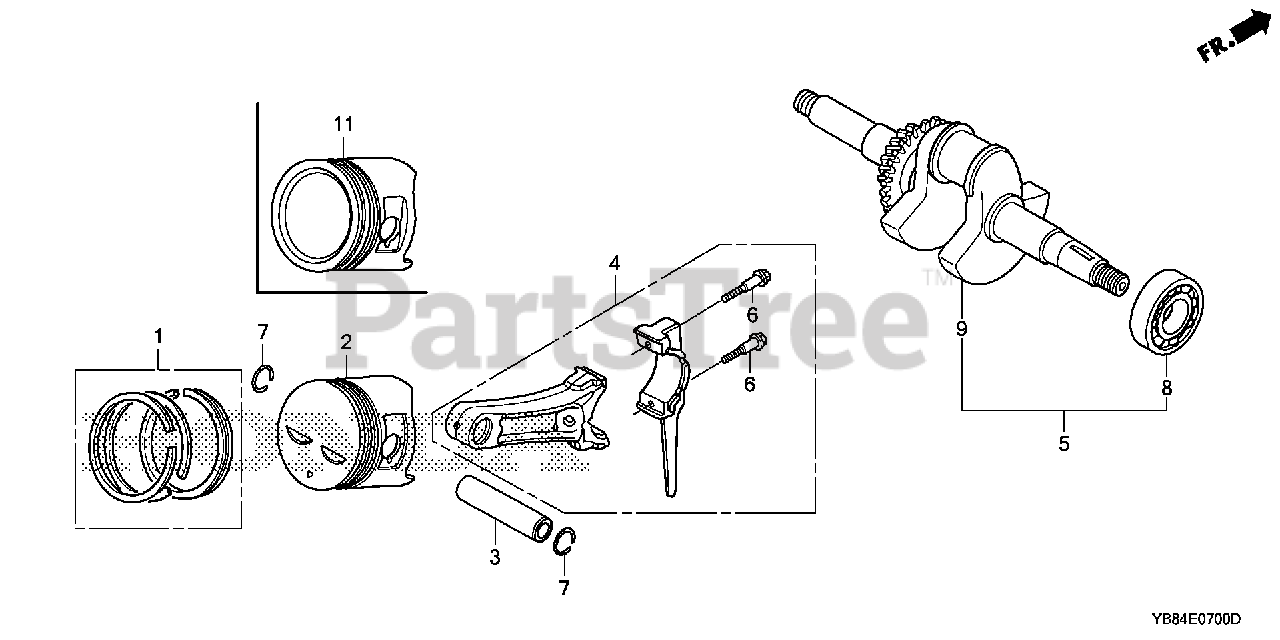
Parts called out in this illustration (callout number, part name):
1	RING SET, PISTON (STD) (TEIKOKU)
1	RING SET, PISTON (0.25) (TEIKOKU)
1	RING SET, PISTON (0.50) (TEIKOKU)
1	RING SET, PISTON (0.75) (TEIKOKU)
3	PIN, PISTON
4	ROD ASSY., CONNECTING (STD)
4	ROD ASSY., CONNECTING (0.25 LOWER SIZE)
5	CRANKSHAFT
6	BOLT, CONNECTING ROD
7	CLIP, PISTON PIN (18MM)
8	BEARING, RADIAL BALL (6206 SH)
11	PISTON (STD)
11	PISTON (0.25)
11	PISTON (0.50)
11	PISTON (0.75)
